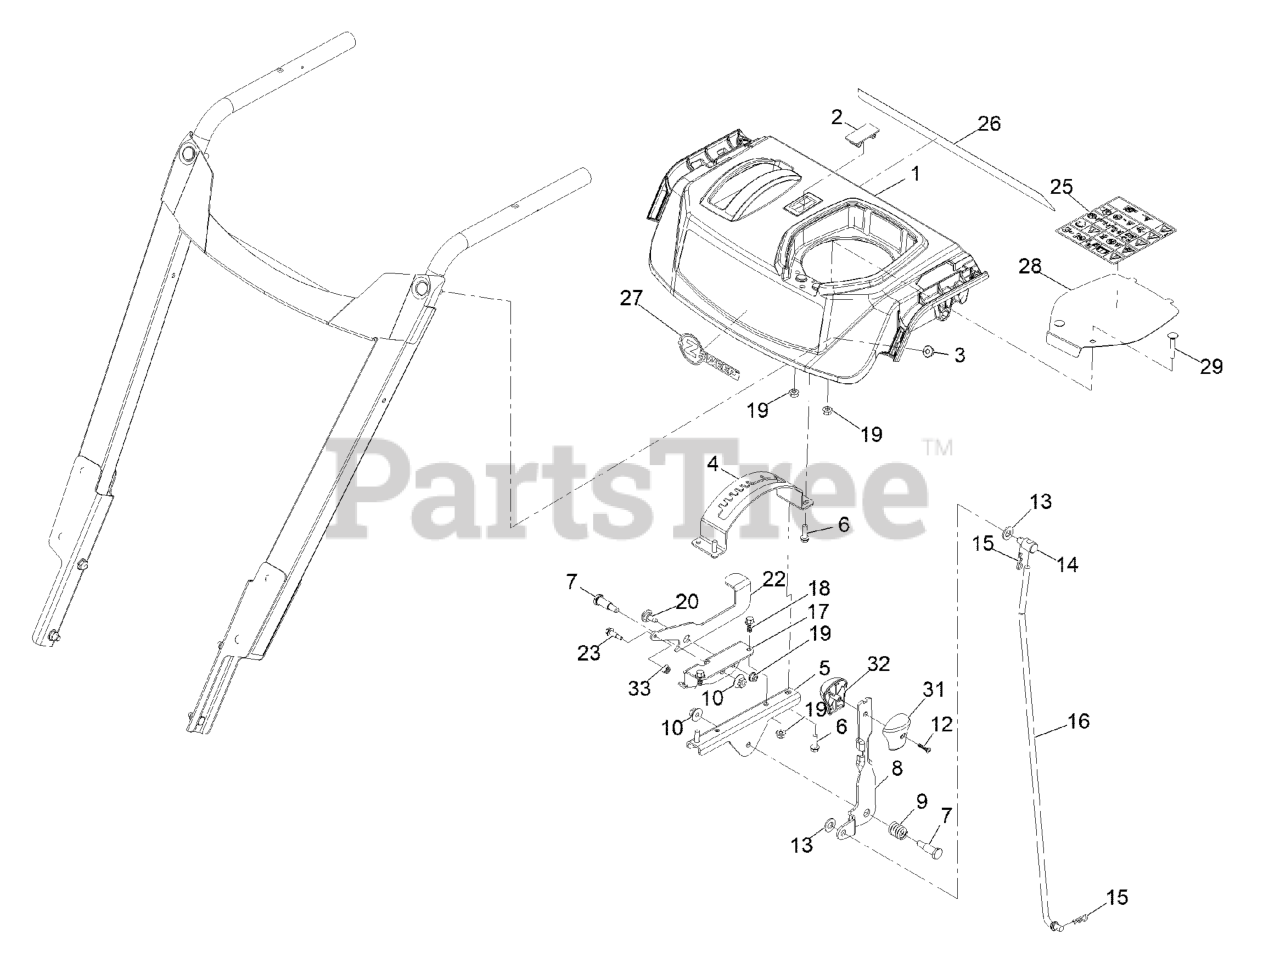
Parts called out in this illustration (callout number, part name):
1	PANEL-CONTROL
2	PLUG-HOLE
4	GATE-SHIFT
5	BRACKET-SHIFT
6	SCREW-PLASTITE, HWH
7	SCREW-SHOULDER, HH
8	SELECTOR-SPEED
9	SPRING-COMPRESSION
12	SCREW-PPH
13	WASHER-FLAT
14	TRUNNION-ROD
15	PIN-HAIR
16	ROD-SHIFT
17	BRACKET-LEVER, BROOM ANGLE
18	Screw-HHF 1/4-20 X 5/8
19	SCREW-SHOULDER
20	SCREW-SHOULDER
22	LEVER-BROOM ANGLE
23	SCREW-SHOULDER
25	PLATE-COVER, CONT PNL
26	BOLT-CARR
27	KNOB-SHIFT, LH
28	PLATE-COVER, CONT PNL
29	BOLT-CARR
31	KNOB-SHIFT, LH
32	KNOB-SHIFT, RH
